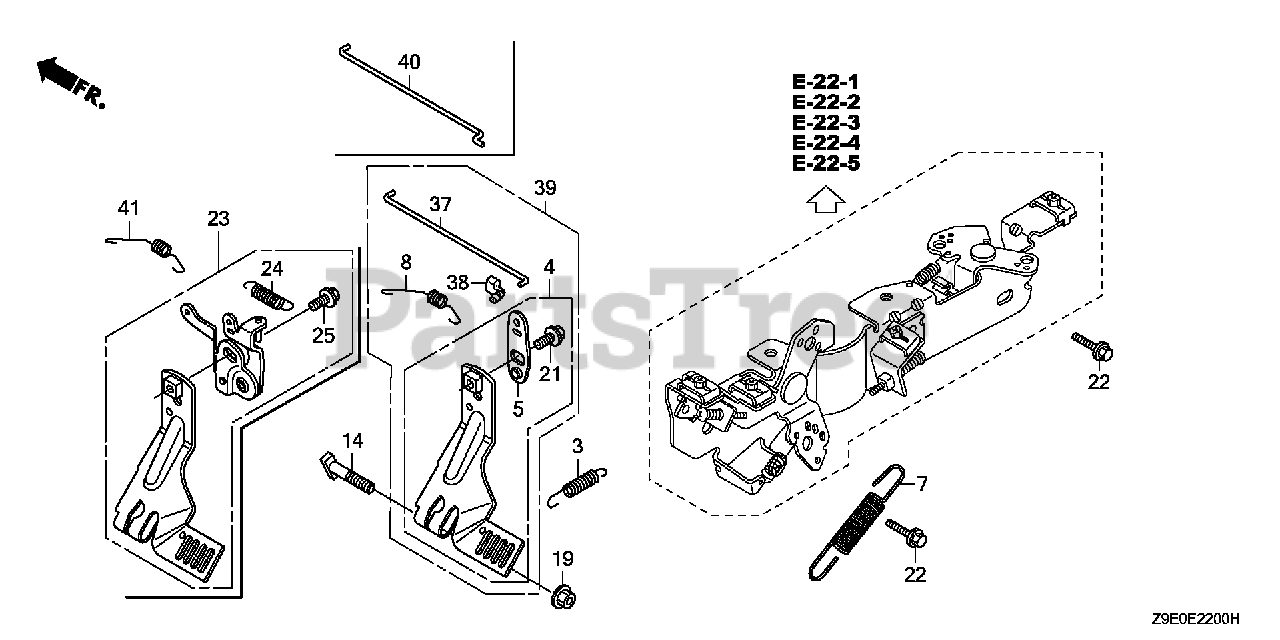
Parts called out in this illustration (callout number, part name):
3	SPRING, STARTER
7	SPRING, GOVERNOR
14	BOLT, GOVERNOR ARM
19	NUT, FLANGE (6MM)
22	BOLT, FLANGE (6X14)
23	ARM, GOVERNOR
24	SPRING, RETURN
25	BOLT, FLANGE (6X10)
40	ROD, GOVERNOR
41	ARM KIT, GOVERNOR
41	SPRING, THROTTLE RETURN
